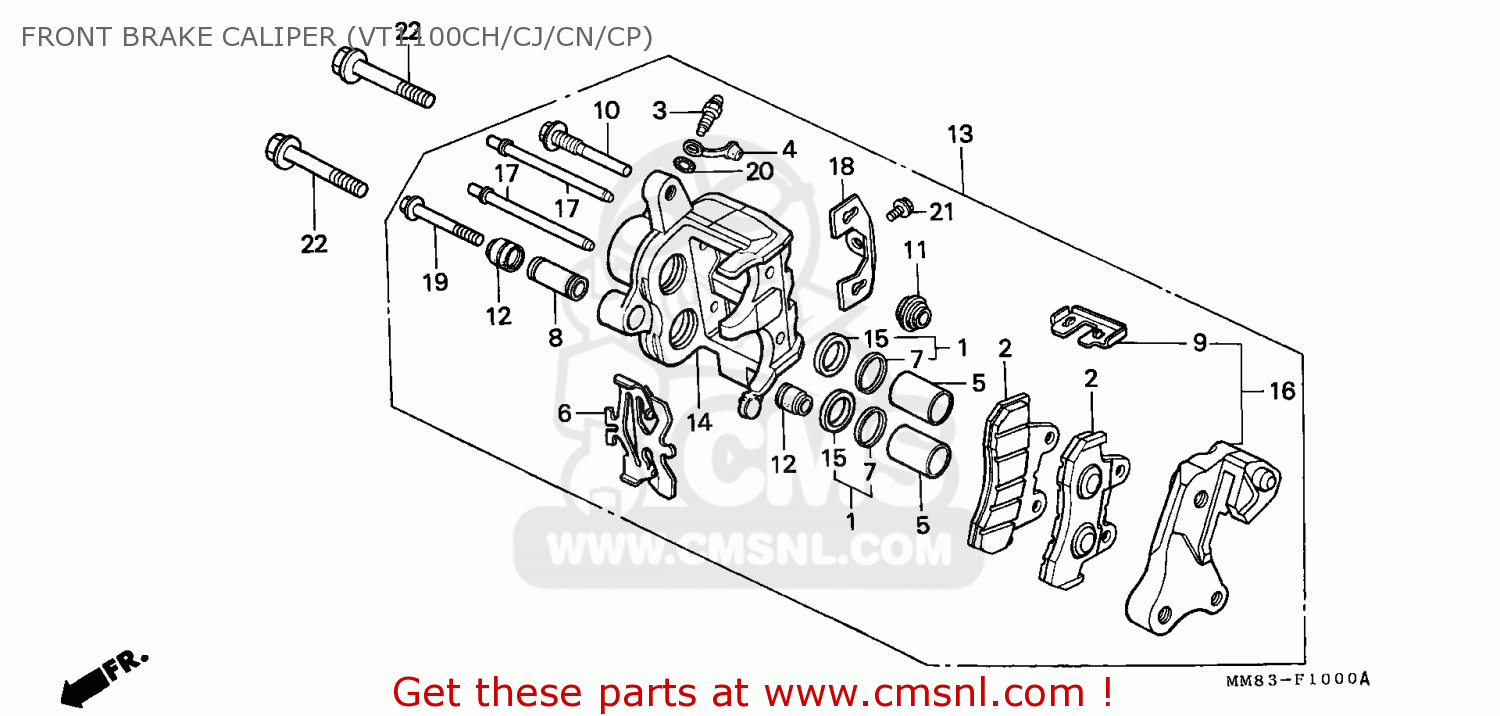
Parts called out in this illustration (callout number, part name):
2	PAD COMP,RR (TT) (NAS)
3	SCREW,BLEEDER
4	CAP,BLEEDER
5	PISTON
6	SPRING,PAD
7	DUST SEAL
8	SLEEVE
9	BRACKET RETAINER
10	PIN,BOLT
11	BOOT B
12	BOOT,PIN
13	CALIPER ASSY,R FR
14	CALIPER COMP.,L.F
15	SEAL,PISTON
16	BRACKET COMP,R FR
17	PIN,HANGER
18	PLATE
19	BOLT,FLANGE 8X49
20	O-RING
21	BOLT,FLANGE,SH 6X10
22	BOLT,FLANGE,10X40
